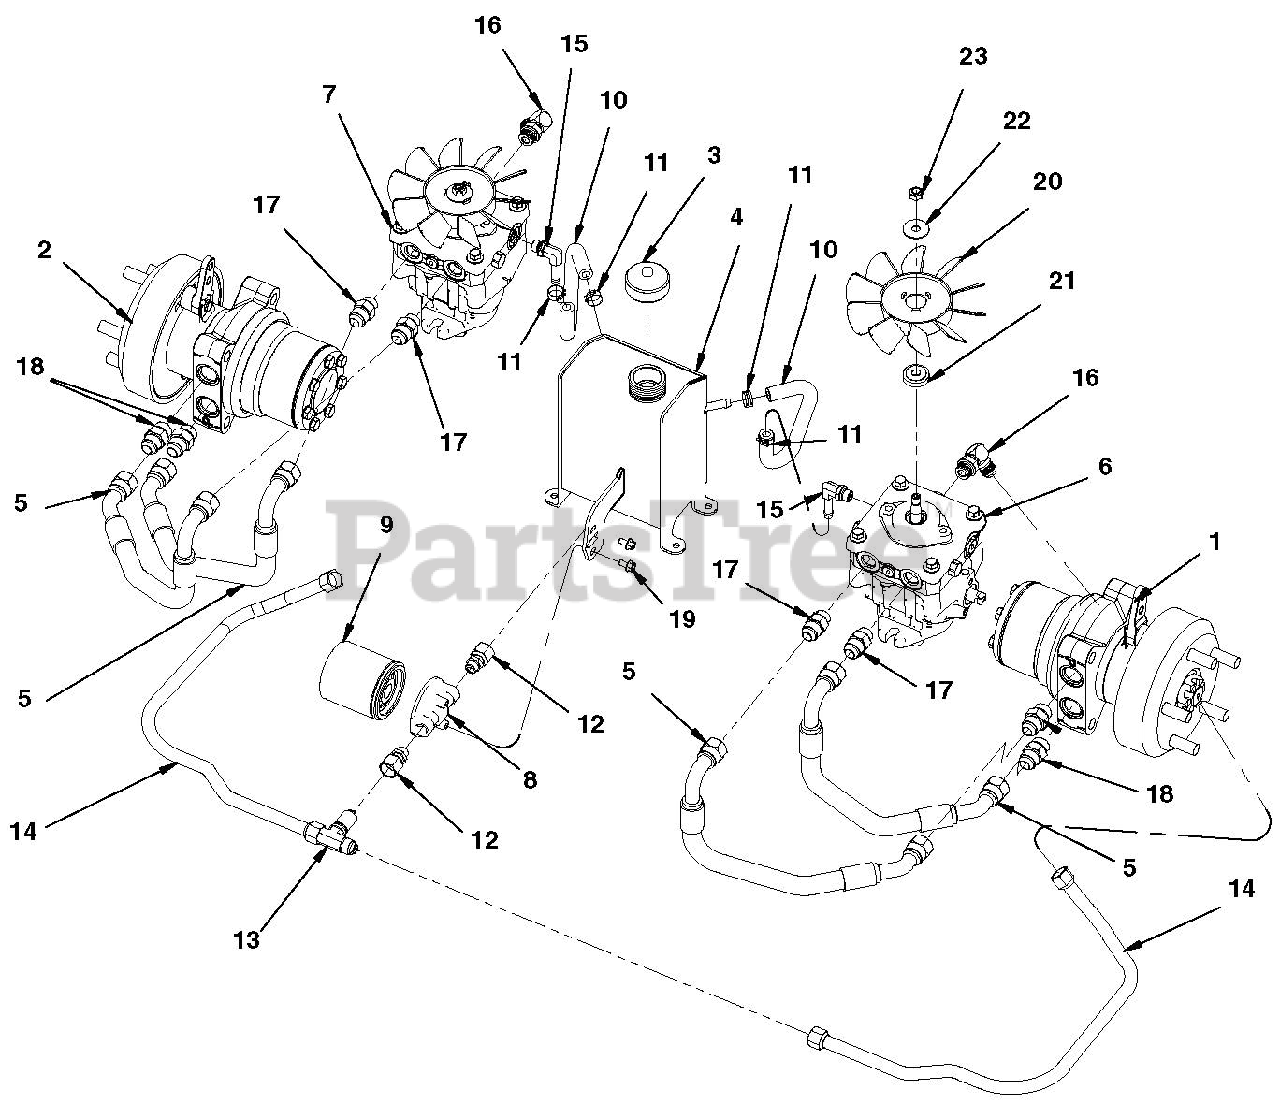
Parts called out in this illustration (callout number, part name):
1	MOTOR, LH HYDRO GEAR WHEEL
2	MOTOR, RH HYDRO GEAR WHEEL
3	CAP, OIL RESIVOIR W/FREE FLOW
4	WLDT, OIL TANK
5	HOSE, HYD-10 -10FJIC90/45 18
6	PUMP, HYDRO LH PR-2HDD
7	PUMP, HYDRO RH PR-2KDD
8	HEAD, OIL FILTER
9	FILTER, 25 MICRON
10	HOSE, HYD 3/8 X 12.50
11	CLAMP, HOSE - 11/16 SPRING
12	FTG, ADP 9/16-18MORX3/4-16FJIC
13	FTG, TUN 3/4-16JIC
14	HOSE, HYD-8 -12FJIC 29
15	FTG, 90 9/16MOR X 3/8HOSE
16	FTG, 90 ADP JIC-ORB 6801-08-08
17	FTG, ADP 3/4MORX7/8MJIC
18	FTG, ADP 7/8-14MORX7/8-14FJIC
19	BOLT, 1/4-20X.500 WSH 5 Y
20	FAN, BDP16 PLASTIC COOLER
21	HUB, BDP16 FAN
22	WASHER, .375X1.25X.072 BLVL U
23	LOCKNUT, 3/8-24 CROWN Y
